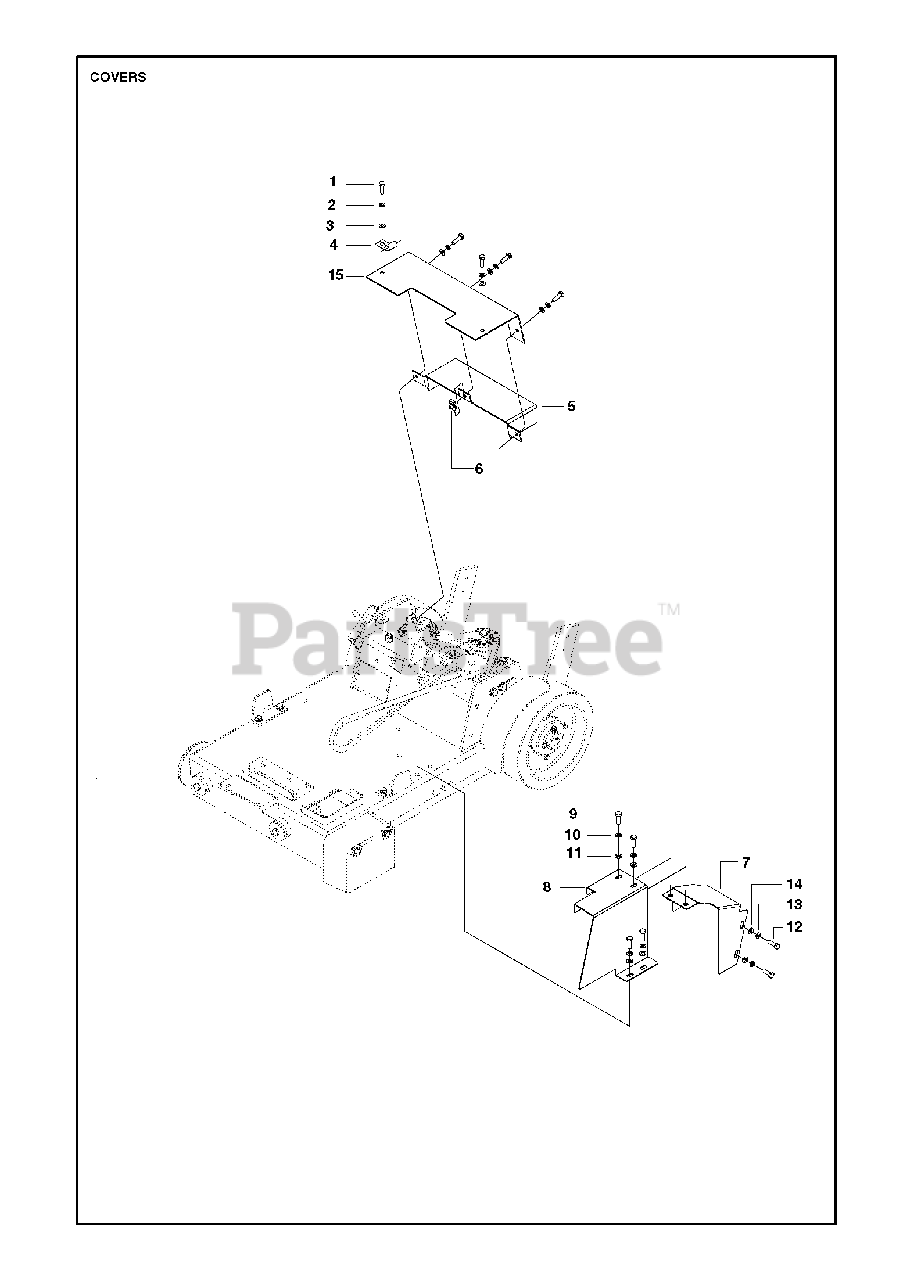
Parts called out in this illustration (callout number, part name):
2	SPRING WASHER
3	WASHER
10	SPRING WASHER
11	WASHER
13	SPRING WASHER
14	WASHER
